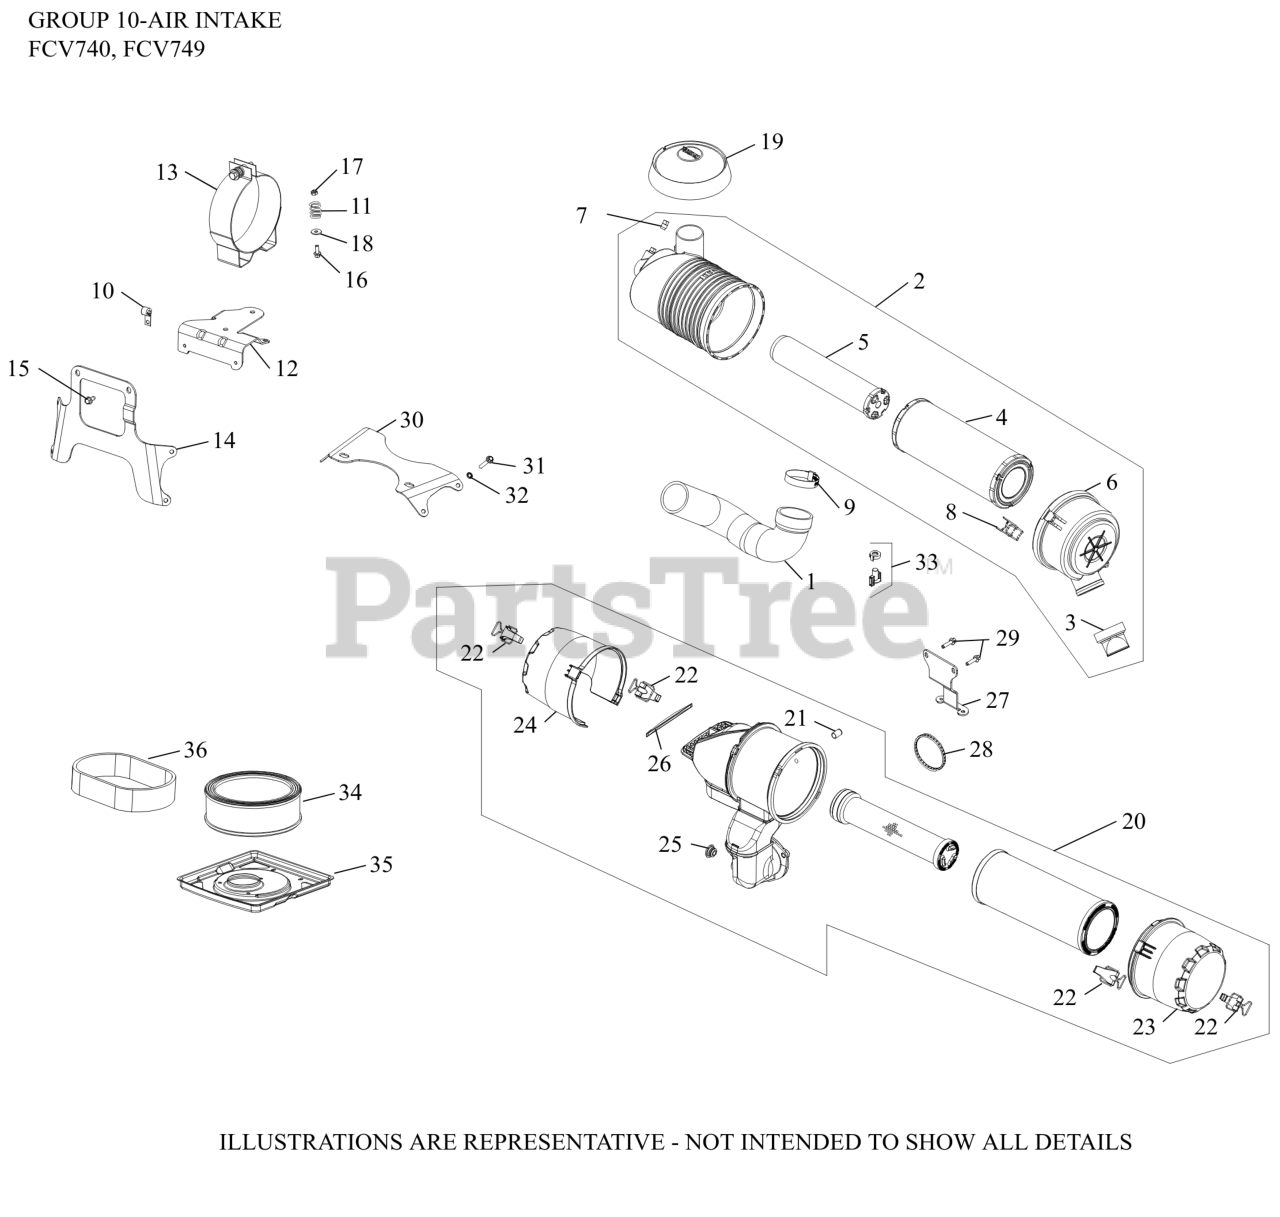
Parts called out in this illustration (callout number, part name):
4	ELEMENT, AIR FILTER - PRIMARY
5	ELEMENT, AIR FILTER - SAFETY
10	CLIP, CABLE
16	SCREW, FLG M6X1.0X16
20	FILTER AIR ASSEMBLY, OIL FILTER SIDE
21	CAP, MASKING
22	CLIP ASSEMBLY
23	COVER, AIR FILTER W/O LOGO
24	COVER, RAIN CAP W/O LOGO
25	PLUG, HOLE
26	DAMPER, FOAM INSERT
27	BRACKET, SUPPORT
28	O-RING (HDAC SEAL-EFI)
29	SCREW, FLG M6X1.0X25
30	BRACKET, MAIN SUPPORT
32	WASHER,INT EXT TOOTH LOCK 1/4"
NI	KIT, HARNESS
NI	FUEL HOSE ASSY (90? FITTING)
